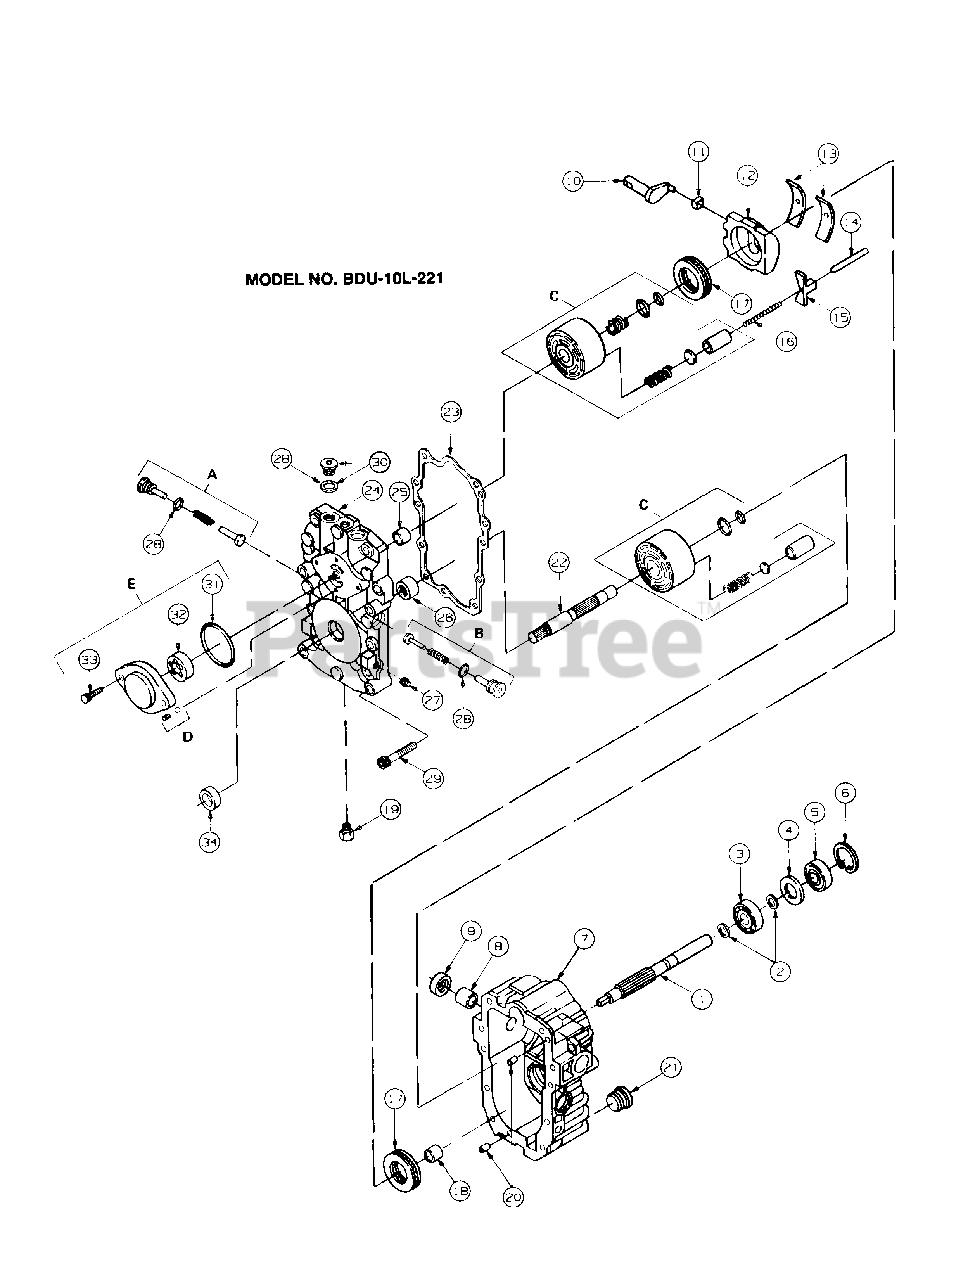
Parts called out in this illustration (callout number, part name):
1	Shaft, Pump
2	Ring, Retaining
3	Bearing, Ball
4	Spacer
5	Seal, Lip
6	Ring, Retaining
7	Housing Assy
8	Bearing, Journal
9	Seal, Lip
10	Arm, Trunnion
11	Guide, Slot
13	Bearing, Cradle
15	Leveler, Swashplate
16	Spring, Leveler
17	Bearing, Thrust
18	Bearing, Journal
22	Shaft, Motor
23	Gasket, Center Section
24	Center Section Assy
25	Bearing, Journal
26	Bearing, Needle
28	O-Ring
29	Screw, Socket Hd
31	O-Ring
32	Gerotor Assy.
33	Screw, Socket Hd
34	Not Used In This Application
A	Kit, Check Valve
B	Kit, Orificed Check Valve
C	Kit, Cylinder Block
D	Kit, Charge Relief Valve
E	Kit, Charge Pump
